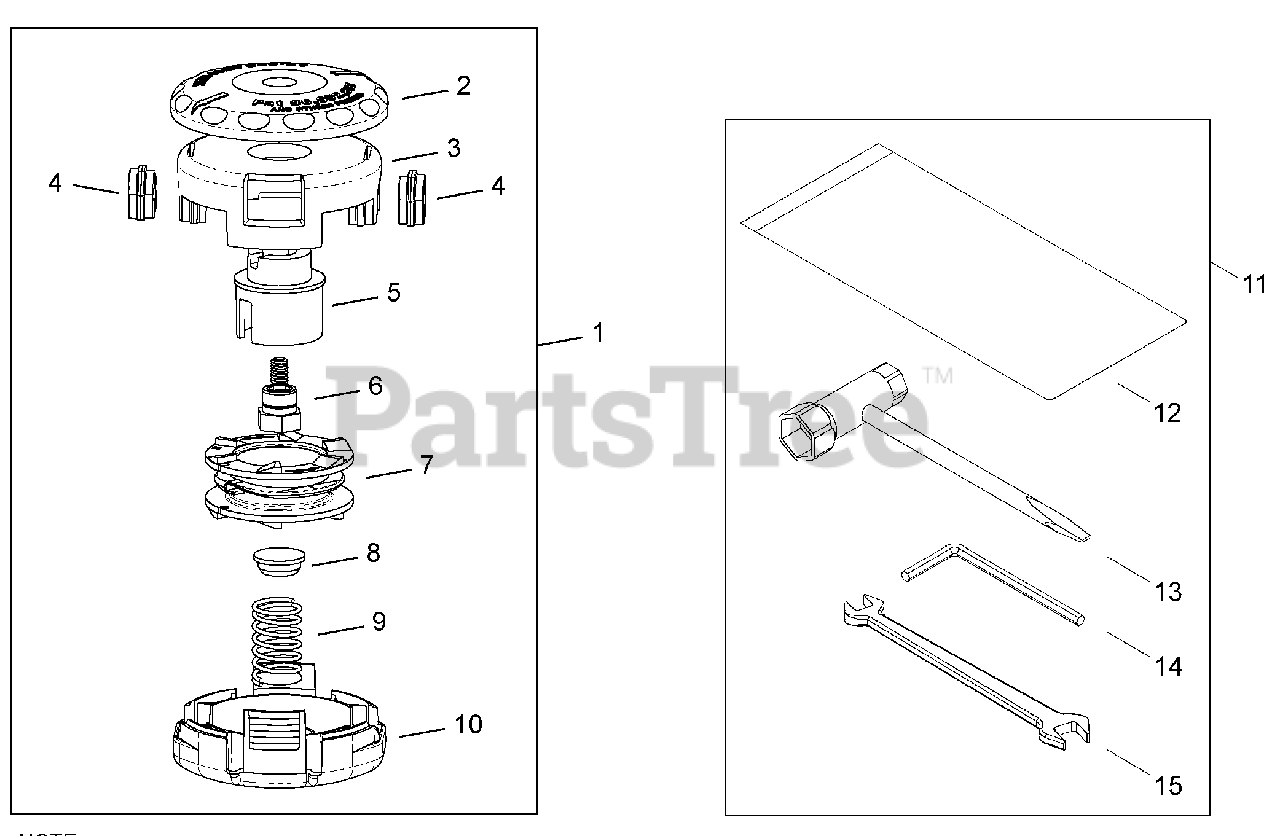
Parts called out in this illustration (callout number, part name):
2	KNOB
3	HOUSING, SPOOL
4	EYELET
5	CORE
6	BOLT, ARBOR 7 MM×1.0 LH
7	SPOOL LH
8	CAP, SPRING
9	SPRING
10	COVER
11	TOOL KIT, SERVICE
12	BAG, TOOL
13	T-WRENCH 13×19 MM
13-1	TRIMMER HEAD, SPEED-FEED® 375
14	WRENCH, ALLEN 4 MM
15	SPANNER 8×10
